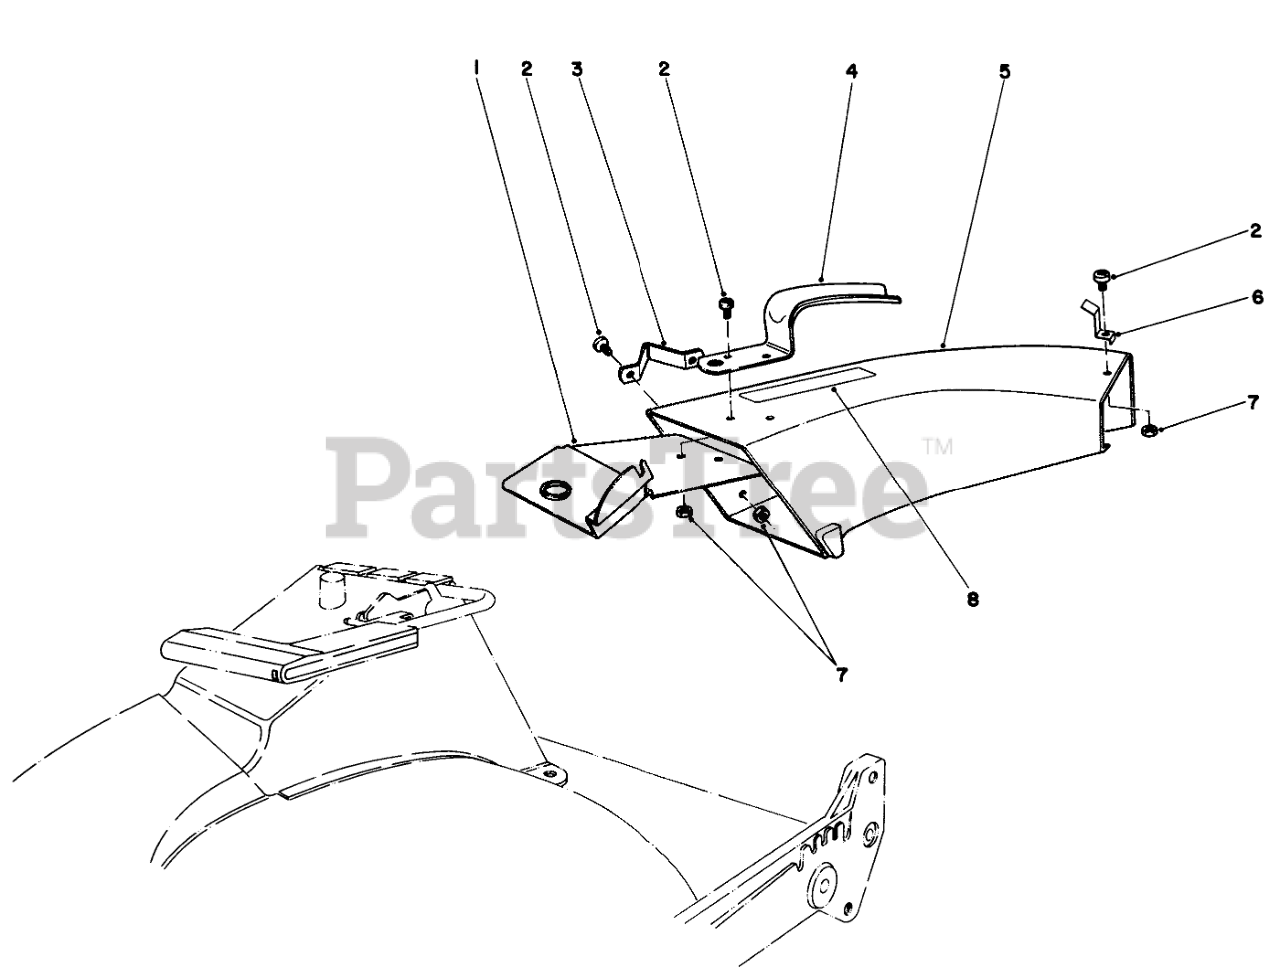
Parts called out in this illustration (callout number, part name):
1	Plate-Discharge Chut
2	10-24 X 5/8 PAN HD MS
3	SIDE BRACKET
4	CHUTE HANDLE
5	Chute-Discharge (Incl. Ref. #8)
7	NUT-LOCK, NI
8	DECAL CAUTION
